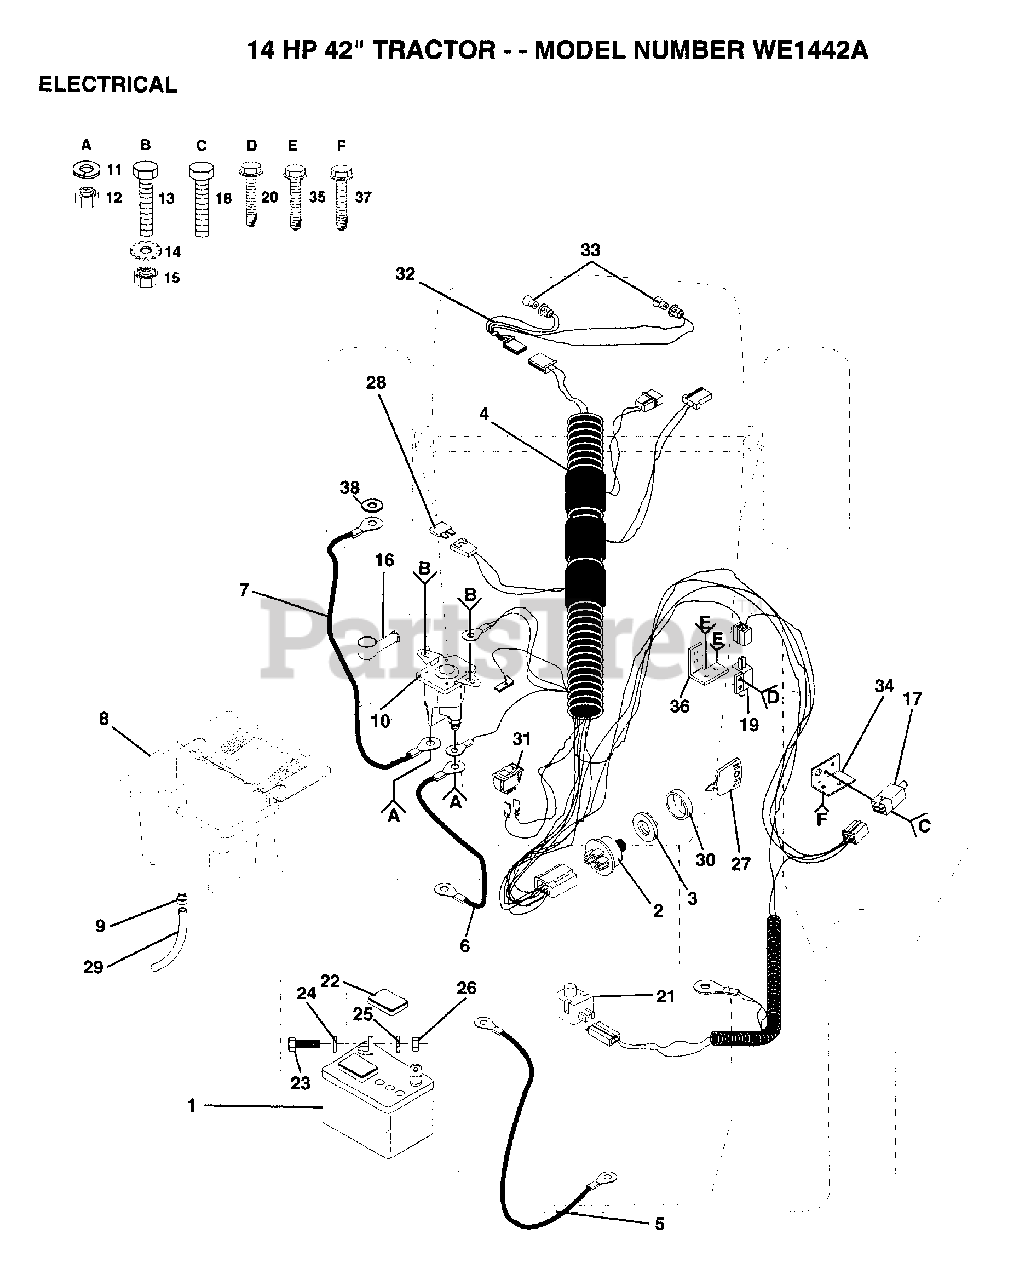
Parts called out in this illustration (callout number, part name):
3	NUT IGNITION
4	IGN HARNESS
5	CABLE T
7	"CABLE T, BATTERY"
9	HOSE CLAMP T
12	NUT
13	BOLT
15	NUT
17	SWITCH INTERLOCKT
18	SCREW
19	SWITCH-INTER. GT
20	SCREW
21	SWITCH SEAT
22	"CAP,BATTERY "
23	BOLT LT
24	WASHER
25	LOCKWASHER
27	KEY
28	FUSE HYT
29	TUBE T
31	SWITCH LT
32	"HARNESS,LIGHT SOC"
33	HEADLAMP BULB
34	BRACKET LT
35	SCREW
36	SWITCH BRACKET
37	SCREW
38	LOCKWASHER
